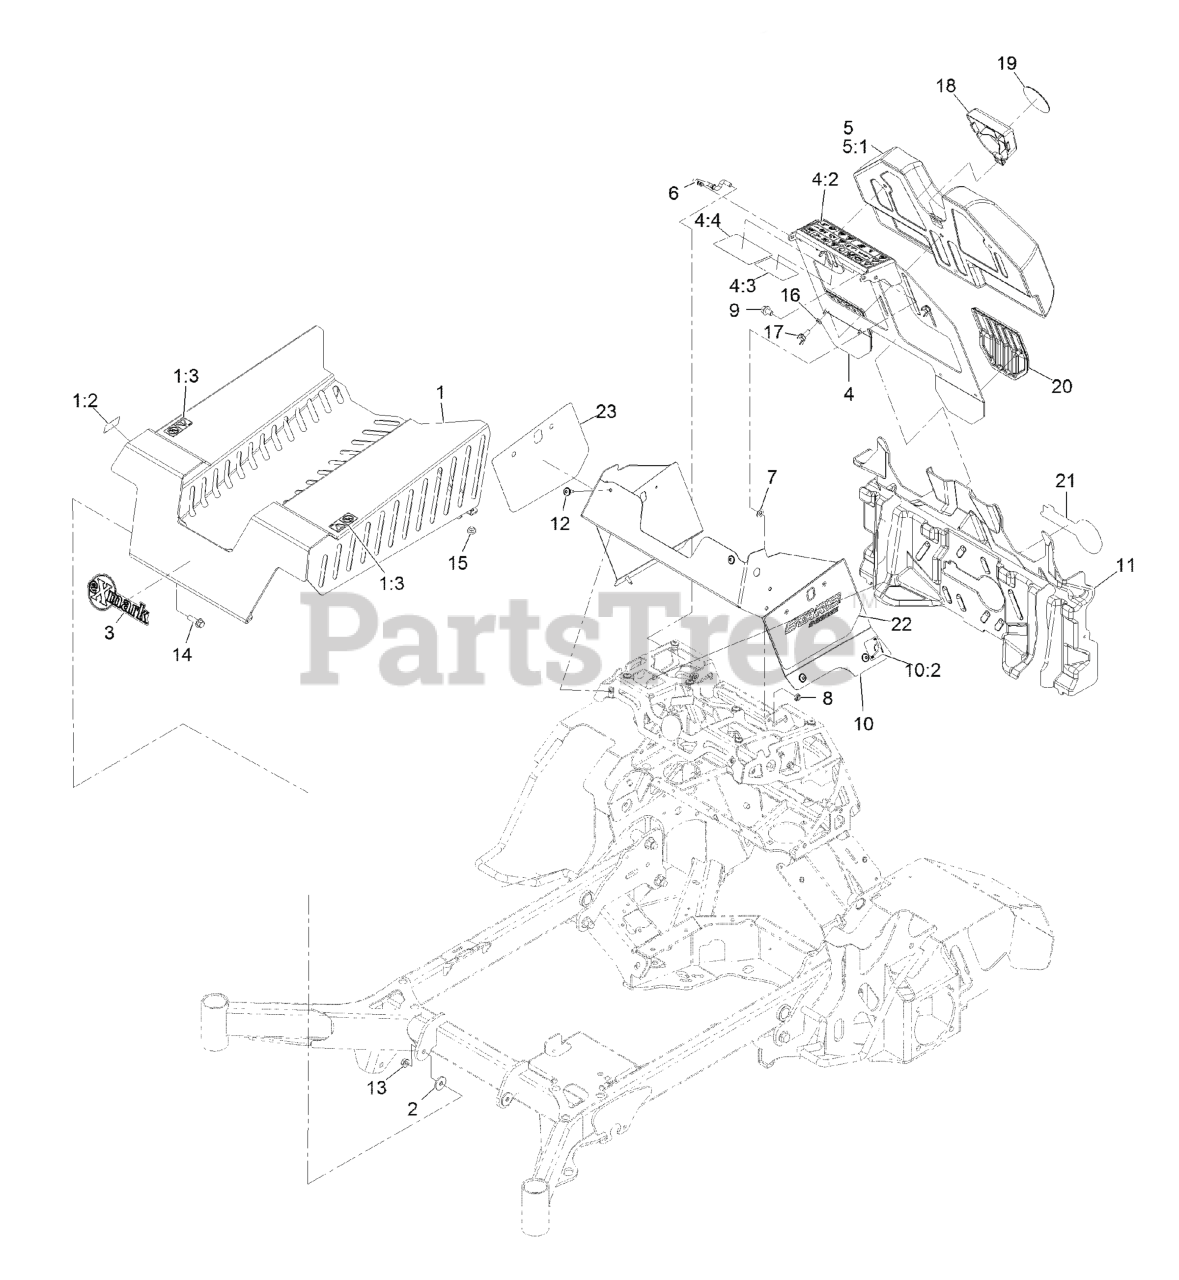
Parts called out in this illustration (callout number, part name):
1	ASM, FRONT COVER W/ DECALS
1:2	DECAL-WARNING
1:3	Decal-Warning
2	WASHER
3	DECAL, EXMARK LOGO
4	ASM, PAD BACKING W/ DECALS
4:2	DECAL-WARNING
4:3	DECAL-DRIVE RELEASE
4:4	DECAL-SERVICE AID
5	PAD, THIGH
5:1	COVER, PAD
6	ROD, PROP
7	WASHER-THRUST
9	SCREW-HHF
10	ASM, TOWER SKIN W/ DECALS
10:2	DECAL-PARK BRAKE, CE
11	PANEL, HEAT DEFLECTOR
12	SCREW, TORX
14	SCREW-HHF
16	WASHER-BELLEVILLE
17	SCREW, THUMB
18	INSERT, PAD
19	DECAL-X LOGO BADGE 3 IN
20	PAD, KNEE
21	DECAL-EXMARK LOGO
22	DECAL-STARIS LOGO LT
23	DECAL-STARIS LOGO RT
